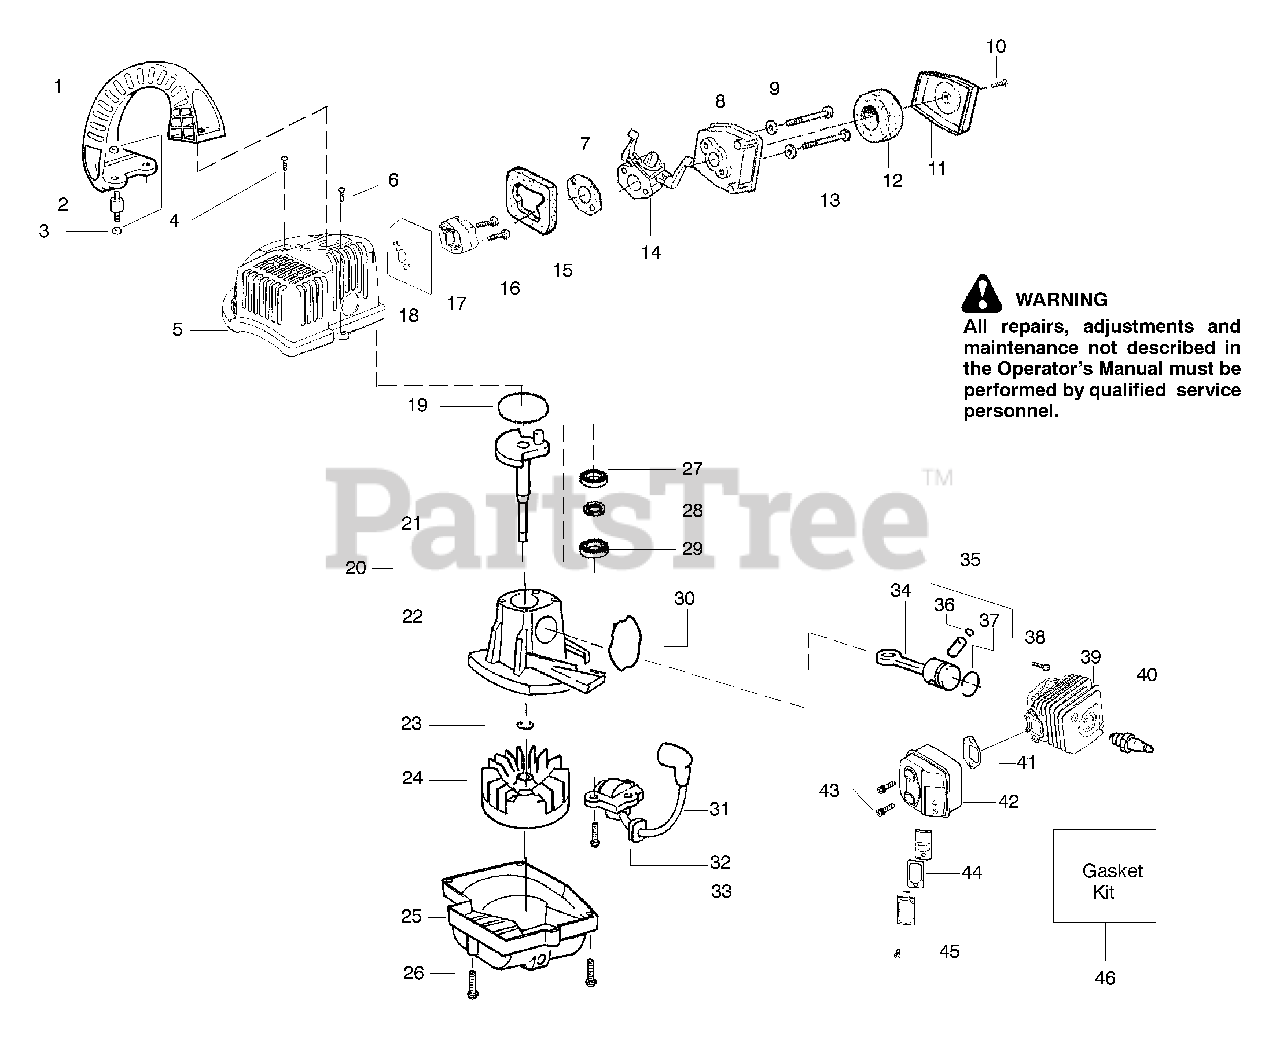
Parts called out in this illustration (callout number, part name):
2	Isolator-Handle
4	Screw
7	Gasket-Carb. (Kit)
11	Cover-Air Box
12	Foam-Air Filter
14	Kit-Carburetor Ass'y. (C1U-W12A)
15	Foam-Air Dam
17	Adaptor-Carb.
18	Gasket-Cyl/Carb. Adaptor (Kit)
19	O-ring-C'case/Shroud (Kit)
20	Assy.-C'case & C'shaft
21	Assy.-Crankshaft
22	Assy.-Crankcase
23	Retainer Ring (C'shaft)
24	Assy.-Flywheel
25	Fan Housing
26	Screw
27	Inner Bearing
28	Seal-Crankcase
29	Bearing-Outer
30	Seal-Cylinder (Kit)
31	Ignition Module
32	Grommet-Ign. Module
34	Kit-Connecting Rod Assy.
35	Kit-Piston
36	Wrist Pin Retainer
37	Piston Ring
39	Cylinder
40	Spark Plug (RCJ-6Y)
41	Gasket-Muffler (kit)
42	Kit-Muffler
43	Bolt-Muffler
44	Kit-Spark Aresstor
46	Kit-Gasket
